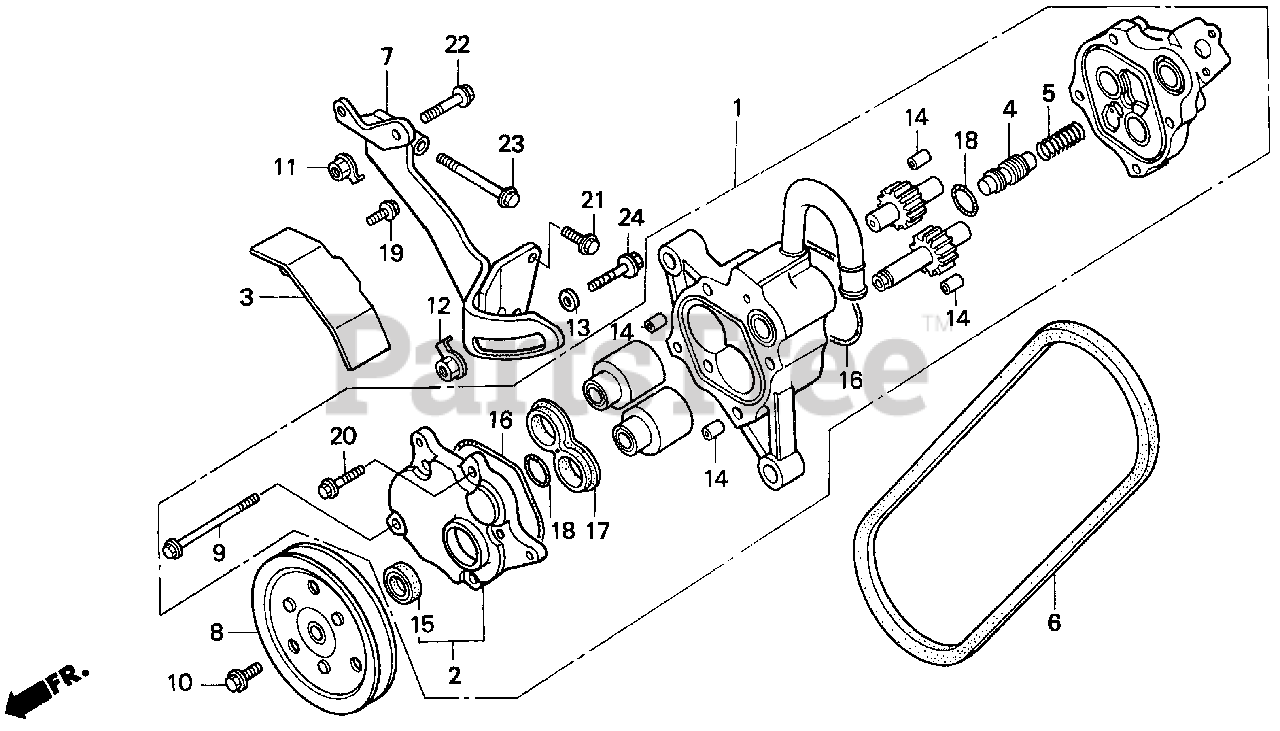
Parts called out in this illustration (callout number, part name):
1	PUMP SUB-ASSY., POWER STEERING
2	COVER, FR. POWER STEERING PUMP
3	COVER, POWER STEERING PULLEY
4	VALVE A, CONTROL
4	VALVE B, CONTROL
5	SPRING, SPOOL
6	BELT, POWER STEERING PUMP (FM-35.5)
7	BRACKET, POWER STEERING PUMP
8	PULLEY ASSY., POWER STEERING PUMP
9	BOLT, FLANGE (6X72)
10	BOLT, SPECIAL (8X18)
11	NUT, PLATE BASED (8MM)
12	NUT, PLATE BASED
13	WASHER (10.2X20)
14	PIN, DOWEL (8X10)
14	PIN A, DOWEL (8X10)
15	OIL SEAL (16X30X7) (NOK)
16	SEAL, HOUSING (ARAI)
17	SEAL, PLUNGER
18	O-RING (19.8X1.9) (NOK)
19	BOLT, FLANGE (6X14)
20	BOLT, FLANGE (6X25)
21	BOLT, FLANGE (8X18)
22	BOLT, FLANGE (8X38)
23	BOLT, FLANGE (8X65)
24	BOLT, FLANGE (10X40)
